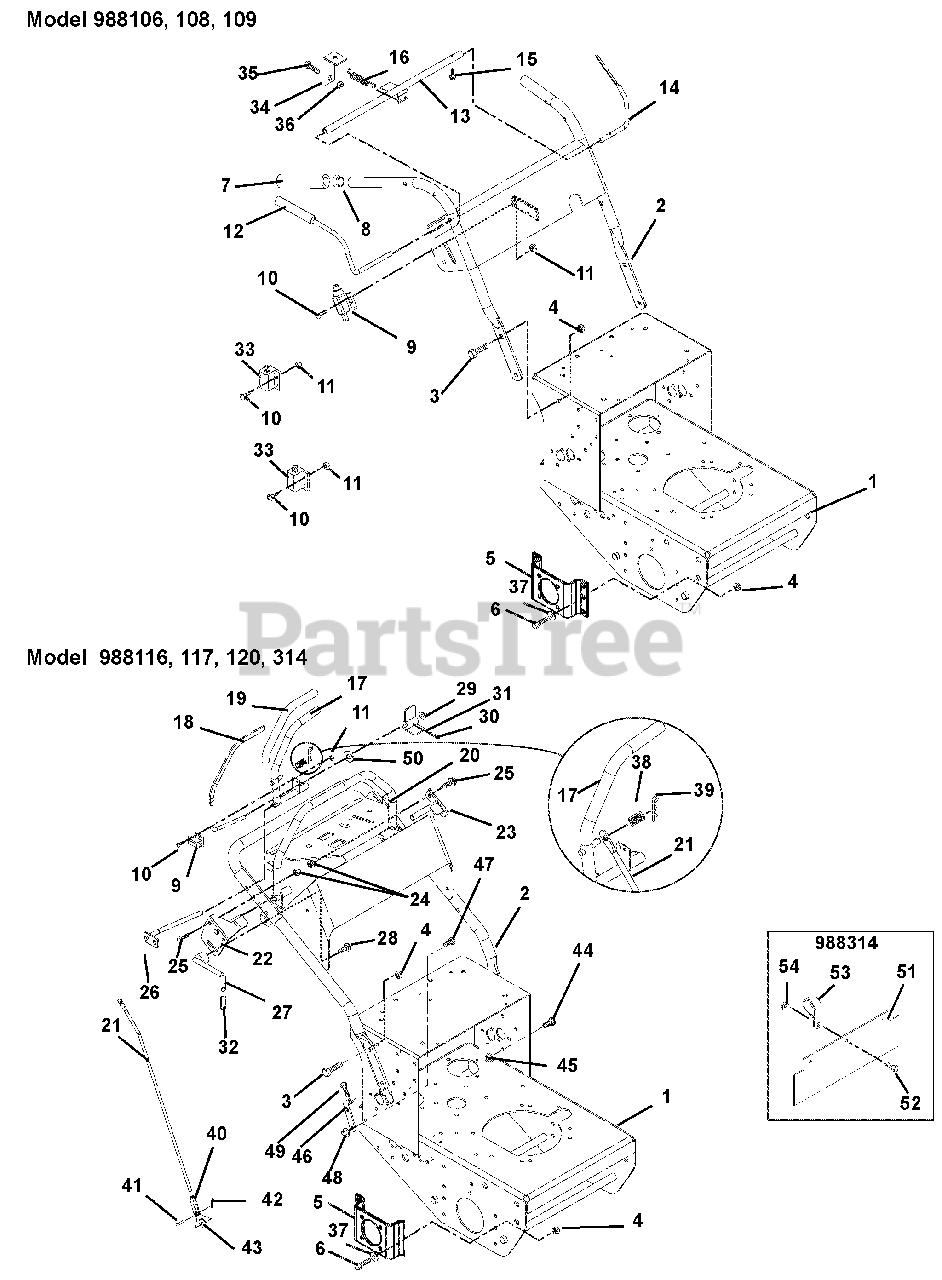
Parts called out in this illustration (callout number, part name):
1	Kit-Frame with Decals
2	Kit-Handlebar with Decals HR15 (106)
3	Bolt-Hex .38-16 x 1.00 Grade 5
4	Nut-Locking-Nylon .38-16
5	Bracket, Wheel Motor Left Hand (108, 116, 120, 314)
6	Bolt-Hex .38-16 x 1.00 Grade 5
7	Grip, Handlebar (106, 108, 109)
8	Caplug, Handlebar (106, 108, 109)
9	Switch, Double Pole(106, 108, 109)
10	Screw, Machine 10-24 x .75 Hex Washer Head (106, 108, 109)
11	Nut-Locking-Nylon 10-24 with Insert (106, 108, 109)
12	Lever, Right Hand-Operator Presence (106, 108, 109)
13	Weldment, Pivot Tube (106, 108, 109)
14	Lever, Left Hand-Operator Presence (106, 108, 109)
15	Screw-Tapping 8-32 x .50 Hex Washer Head (106, 108, 109)
16	Spring-Tension .047 x .438 x 1.45 (106, 108, 109)
17	Weldment, Lever-Right Hand Speed Control (116, 117, 120, 314)
18	Lever- Operator Presence (116, 117, 120, 314)
19	Grip- Handlebar (116, 117, 120, 314)
20	Weldment- Speed Control Stop (116, 117, 120, 314)
21	Rod, Steering (116, 117, 120, 314)
22	Weldment, Control Stop Limiter-Right Hand (116, 117, 120, 314)
23	Weldment, Control Stop Limiter-Left Hand (116, 117, 120, 314)
24	Nut-Locking-Top-Flange .31-18 (116, 117, 120, 314)
25	Bolt-Hex .31-18 x 1.75 Grade 5 (116, 117, 120, 314)
26	Weldment, Speed Control Pivot- Right Hand (116, 117, 120, 314)
27	Lever- Control Stop Lock (116, 117, 120, 314)
28	Bolt-Round Head Square Neck .38-16 x .75 Grade 2 (116, 117, 120, 314)
29	Actuator, Switch (116, 117, 120, 314)
30	Pin-Roll .125 x .75(116, 117, 120, 314)
31	Nut-Push .312 (116, 117, 120, 314)
32	Grip, Hand Clutch Lever (116, 117, 120, 314)
33	Switch- Double Pole N.O./N.O. (106, 108, 109)
34	Bracket, Brake Link (106, 108, 109)
35	Bolt, Hex .25-20 x .75 Grade 5 (106, 108, 109)
36	Nut, Locking Nylon .25-20 (106, 108, 109)
37	Washer, Flat Steel .406 x .812 x .065 (106, 108, 109)
38	Spring-Compression .045 x .60 x .75 (116, 117, 120, 314)
39	Pin-Hair Internal .08 x .18 x 1.18 (116, 117, 120, 314)
40	Yoke, .312-24 x 2.25 (116, 117, 120, 314)
41	Pin-Clevis .31 x .937 (116, 117, 120, 314)
42	Pin-Hair, Endries #25 (116, 117, 120, 314)
43	Washer-Flat-Steel .38 x .87 x .179 (116, 117, 120, 314)
44	Bolt-Hex .31-18 x 1.00 Grade 5 (116, 117, 120, 314)
45	Nut-Spin Lock-Flange .312-18 (116, 117, 120, 314)
46	Weldment- Reverse Adjustment Bracket (116, 117, 120, 314)
47	Bolt-Hex .38-16 x .75 Grade 5 (116, 117, 120, 314)
48	Nut-Locking-Top-Flange .38-16 (116, 117, 120, 314)
49	Bolt-Hex .31-18 x 1.25 Grade 5 (116, 117, 120, 314)
50	Washer, Wave (116, 117, 120, 314)
51	Guard, Debris (314)
52	Bolt-Hex .38-16 x .75 Grade 5 (314)
53	Clamp, Steel 1.0 (314)
54	Nut-Locking-Top-Flange .38-16 (314)
